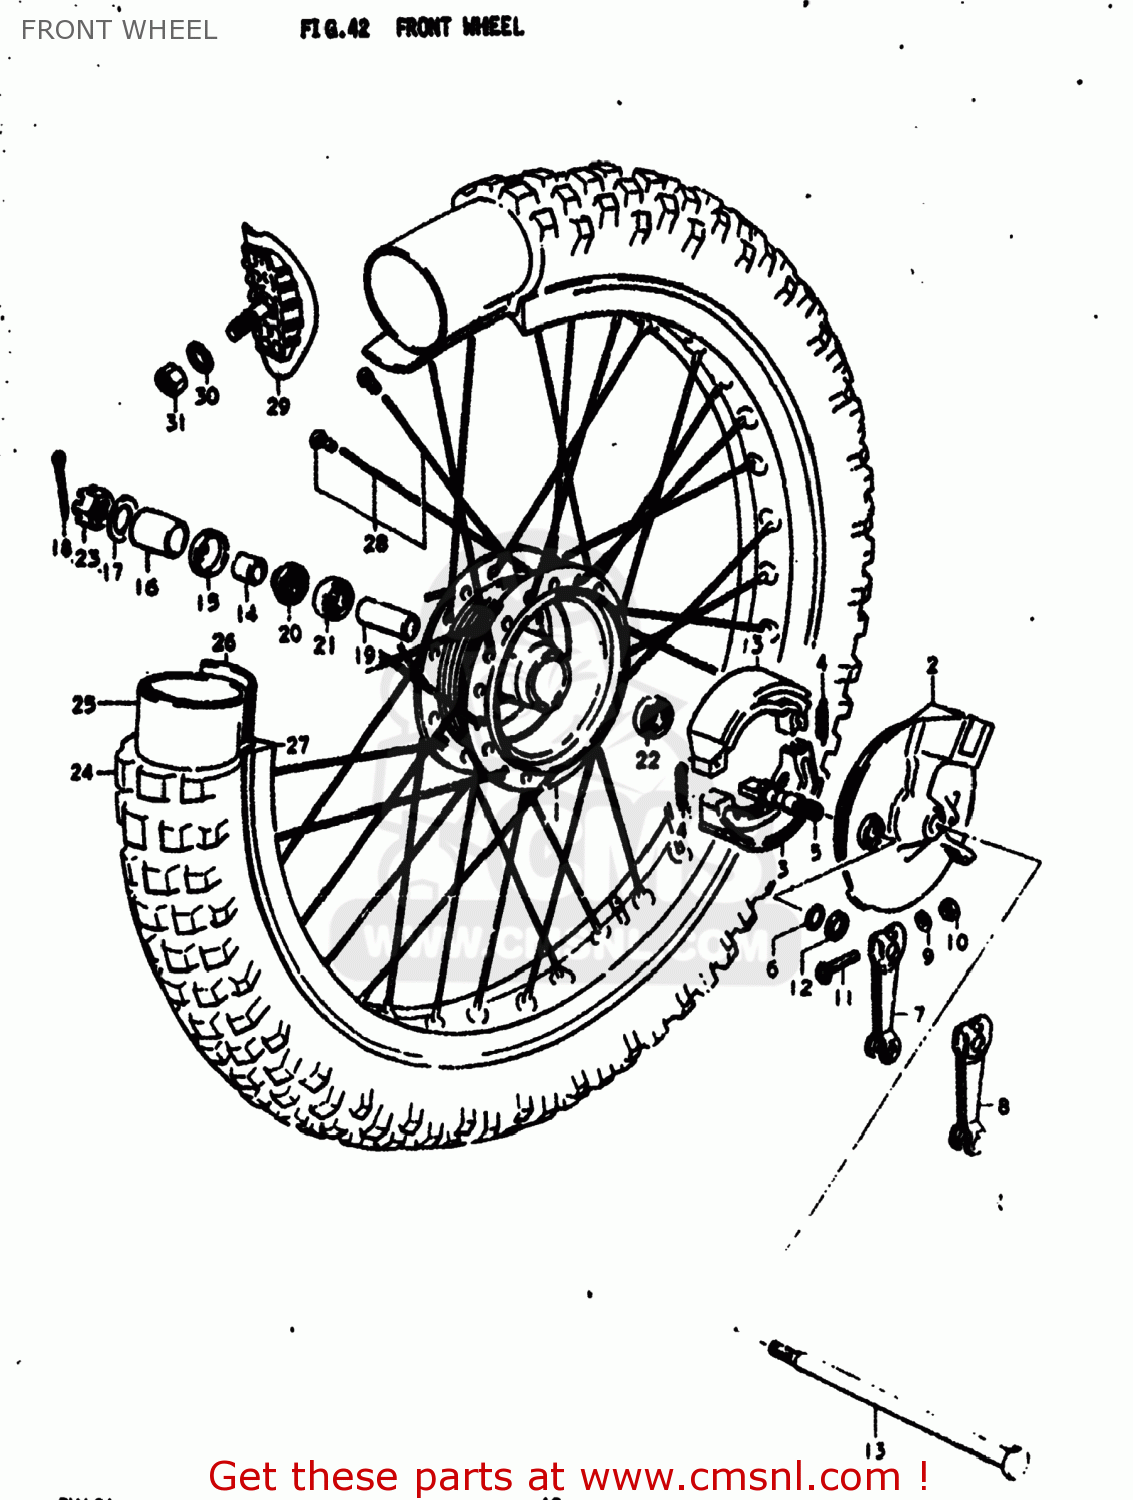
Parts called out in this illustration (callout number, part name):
1	HUB,FRONT
2	PANEL,FRONT HUB
3	SHOE,BRAKE
4	SPRING(L:34)
5	CAM,FR BRAKE
6	O RING(D:2.5,ID:11.4)
7	LEVER,FR BRAKE CAM
8	LEVER,FRONT BRAKE CAM
9	WASHER
10	NUT
11	BOLT
12	WASHER(12.5X20X1)
13	AXLE,REAR
14	SPACER
15	DUST SEAL,FRONT HUB DRUM
16	SPACER
17	WASHER
18	COTTER PIN
19	WASHER
20	OIL SEAL
21	BEARING
22	BEARING, LH
23	NUT 12MM
24	TIRE,FRONT
25	TUBE
26	PROTECTOR,WHEEL,INNER
27	RIM,FRONT WHEEL
28	SPOKE SET,FRONT
29	STOPPER,BEAD
30	WASHER
31	NUT
